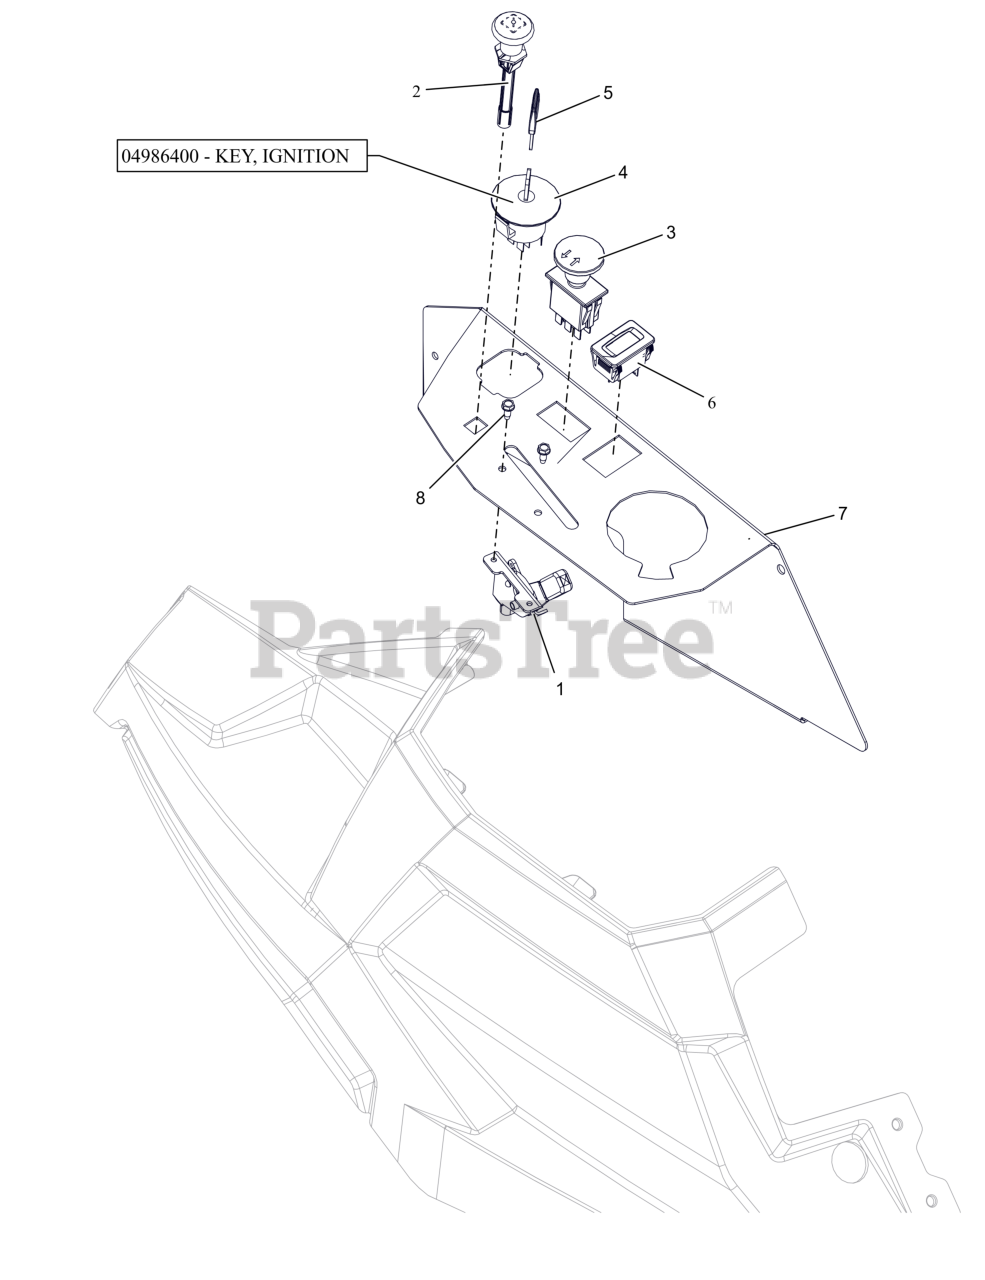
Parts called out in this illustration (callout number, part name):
1	CABLE - THROTTLE CONTROL
2	CABLE - CHOKE, SNAP-IN
3	SWITCH, CLUTCH (YELLOW)
4	KEYSWITCH-IGNITION 4 POS
5	KEY, IGNITION
6	HOUR METER
7	PANEL, CONTROL (RED)
8	SCR,TAP #10-24X.50 HWH TR ZCC
